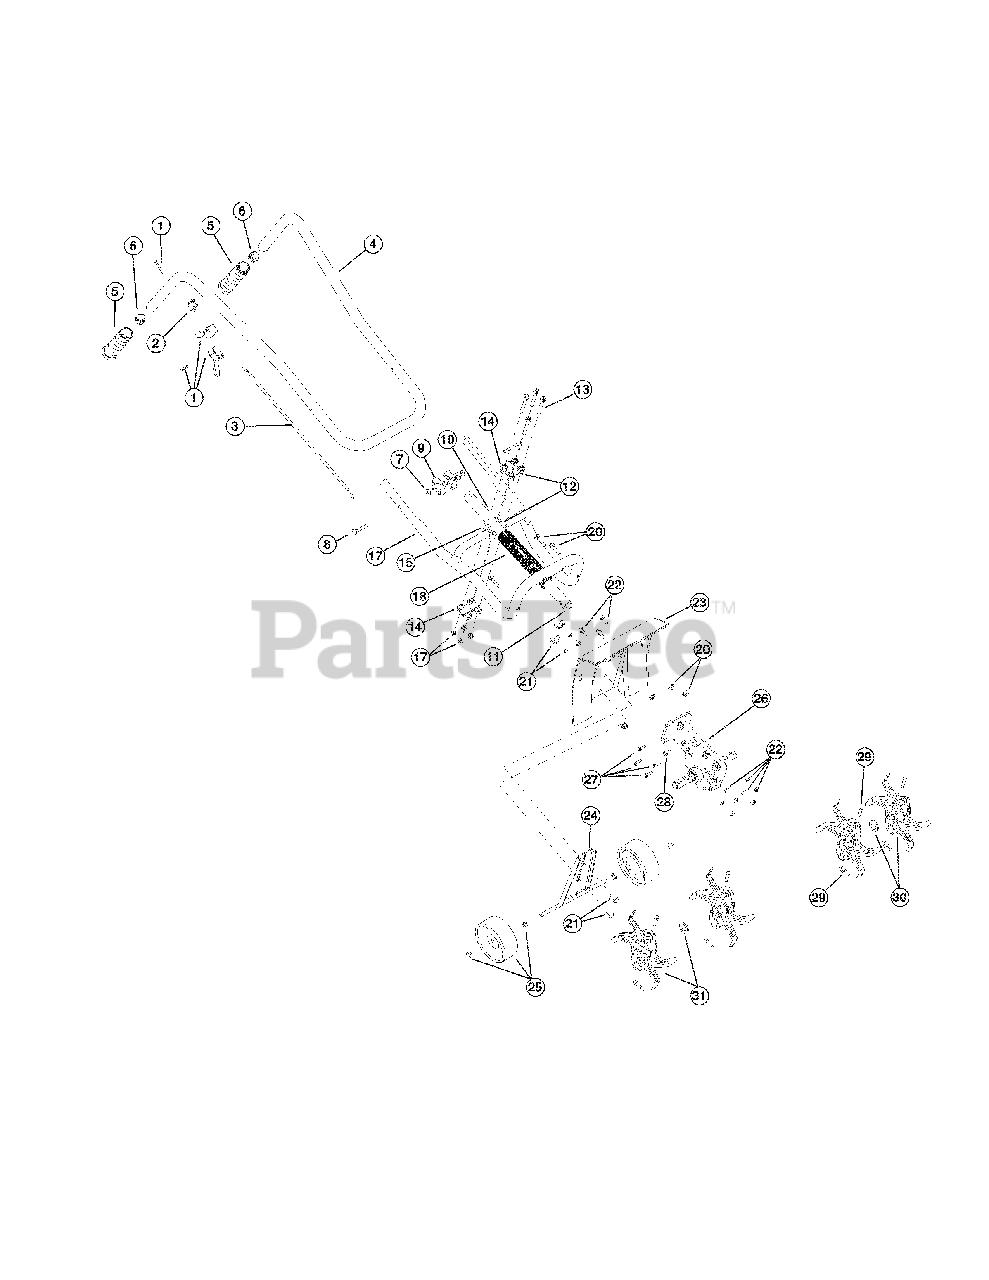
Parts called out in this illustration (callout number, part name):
1	Throttle Trigger Assembly
3	Throttle Cable
4	Handle Bar Assembliy, Upper (includes 5 & 6)
6	Tube Closure
7	Washer
9	Knob, 3 prong
10	Drive Shaft Housing Assembly
11	Flexible Drive Shaft
12	Handle Bracket Assembly (includes 13-17)
14	Upper Handle Clamp
15	Middle Handle Clamp
16	Lower Handle Clamp
19	Lower Handle Bar
20	Hardware, Handle Bar Mounting (lower)
21	Wheel Bracket Mounting Hardware
22	Guard Mounting Hardware
24	Wheel Bracket Assembly (Solid Black Wheels)
25	Wheel Assembly (Black & White Wheels)
25	Wheel Assembly (Solid Black Wheels)
26	Gear Box Assembly
28	Sleeve Retainer Bolt
29	Tine Fastener Assembly
30	Tine Assembly (Left Outer or Right Inner)
31	Tine Assembly (Left Inner or Right Outer)
